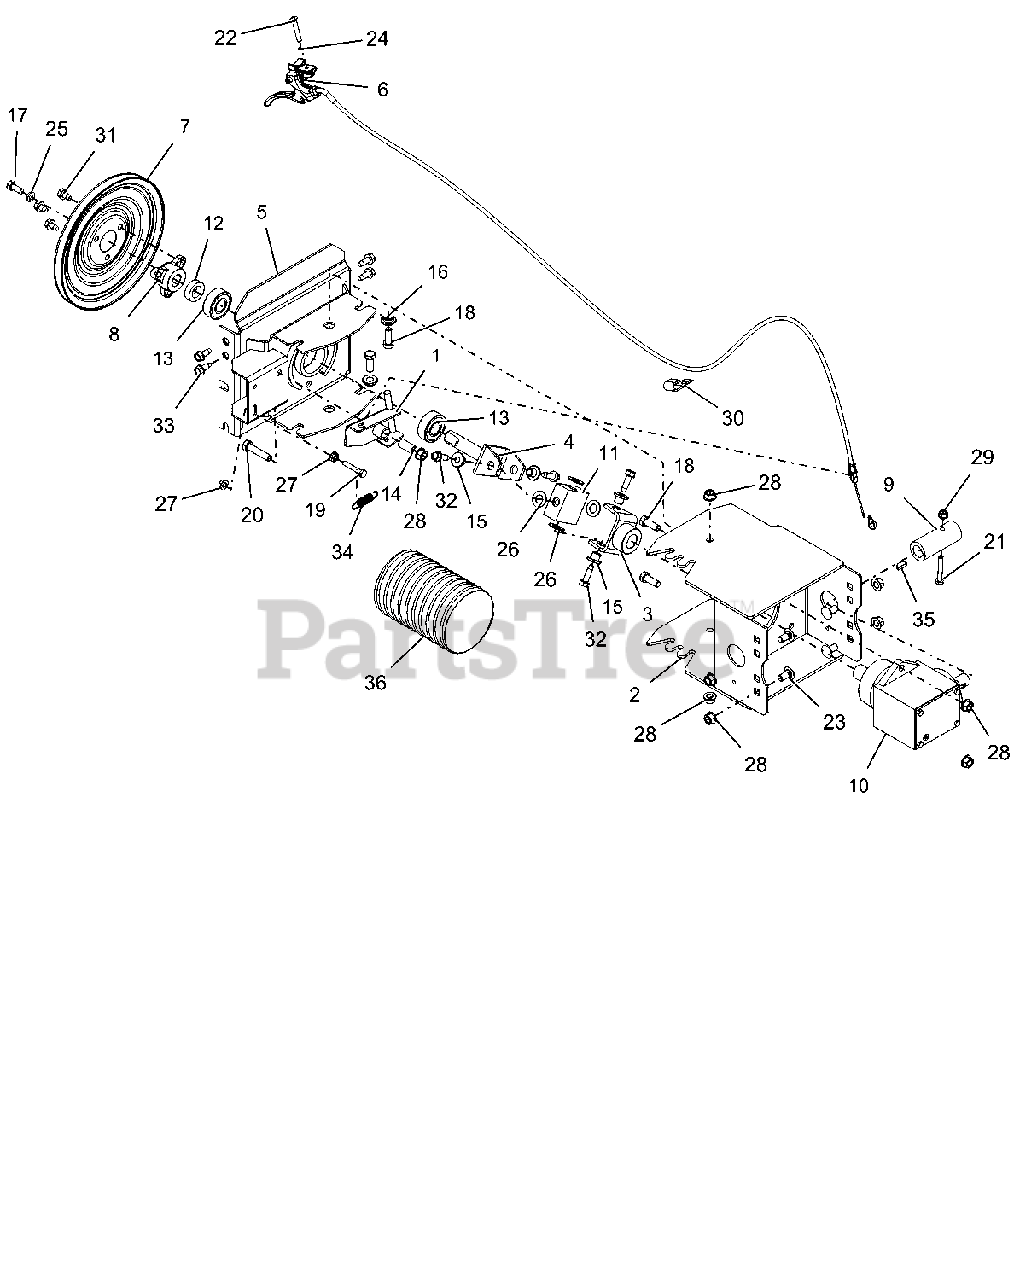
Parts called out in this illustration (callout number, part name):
1	ARM, PIVOT LOCK
2	ADAPTER, BROOM FRAME
3	JOINT,UNIVERSAL
4	JOINT,UNIVERSAL
5	ADAPTER, FRAME-20000 SERIES
6	CABLE, REMOTE BRUSH LOCK
7	PULLEY,SPIN FORM SINGLE GROOVE
8	PULLEY HUB, BOLT-ON D-BORE .75
9	HUB, COUPLING
10	GEAR BOX ASSEMBLY
11	BLOCK, UNIVERSAL
12	SPACER .755X1.250X.370
13	BRG-BALL .750X1.781X.61
14	BSHG-SLV .385X.500X1.045
15	BSHG-FLG .325X.500X.513X.875
16	BSHG-FLG .406X.88X.270X.140
17	BLT-HEX .31-24X.75 YWZC GR5
18	@BLT-HEX .38-16X1.00 GR5 YWZC
19	@BLT-HEX .25-20X1.50 GR5 YWZC
20	@BLT-HEX .38-16X1.75 GR5 YWZC
21	@BLT-HEX .25-20X1.75 GR5 YWZC
22	SCR-MCH .25-20X1.50 OVAL HD
23	@BLT-RDHDSQNK .38-16X.75 G5YZ
24	WSHR-LK-INT .250 TH TYA
25	WSHR-LK .312X.097 HVY YWZC
26	WSHR-HDND-STL-THR.515X.97X.062
27	@NUT-SPNLK-FLG .25-20 YWZC
28	@NUT-LK-TOP-FLG .38-16 YWZC
29	@NUT-LK-TOP-FLG .25-20 YWZC
30	J-CLAMP
31	@SCR-TAP .31-18X.50 HWH TR YWZ
32	@SCR-TAP .31-18X1.00 HWH TR YZ
33	@SCR-TAP .31-18X.75 HWH TR YWZ
34	SG-TENS .06X.46X2.00
35	KEY-WDRF .188X.75X.313 SAE 9
36	HOSE 4" X 7" FLEX TUBE PV
